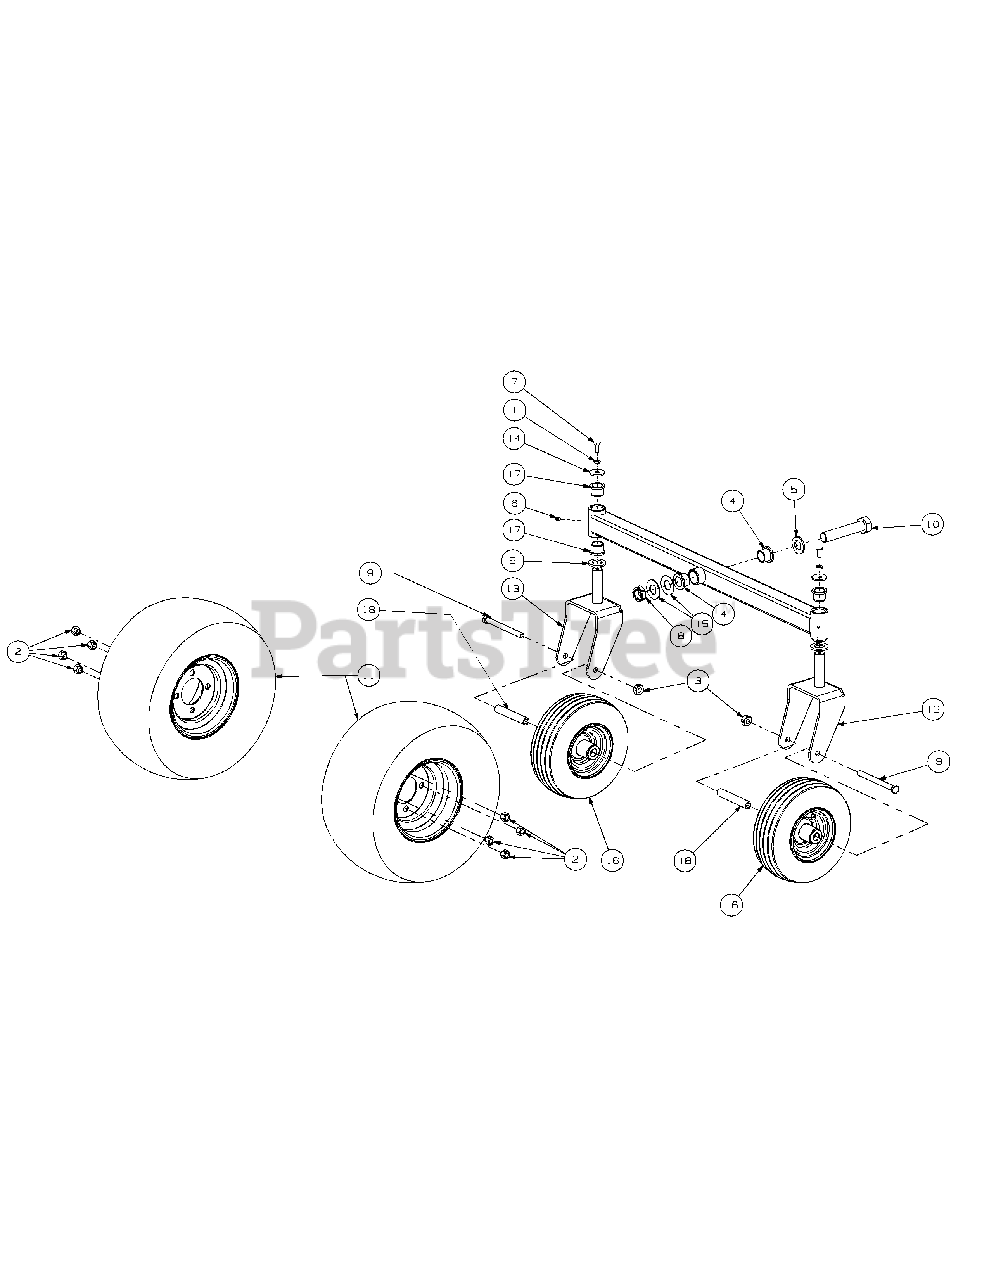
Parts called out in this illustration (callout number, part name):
1	Lock Washer, 3/8 Zinc
2	Lug Nut, 1/2-20
3	Nut, 1/2-20, Center Lock
4	Flange Bearing, 1.001 ID
5	Washer Special
6	Grease Fitting, 1/4-28 x 3/16
7	Hex Cap Screw, 3/8-16 x .88
8	Nut Jam, 1.0-14, Nylon Insert
9	Hex Cap Screw, 1/2-20 x 5.50
10	Hex Cap Screw, 1-14 x 5.5
11	Wheel Assembly, 18 x 8.5
12	Front Axle Assembly
13	Castor Wheel Mounting Bracket
14	Flat Washer, .390 x 1.5 x .134
15	Flat Washer, 1.00 ID x 2.25 OD x ,075
16	Wheel Assembly, 11 x 4 - 4, Beige
17	Flange Bearing, 1.0 ID
18	Wheel Spacer
